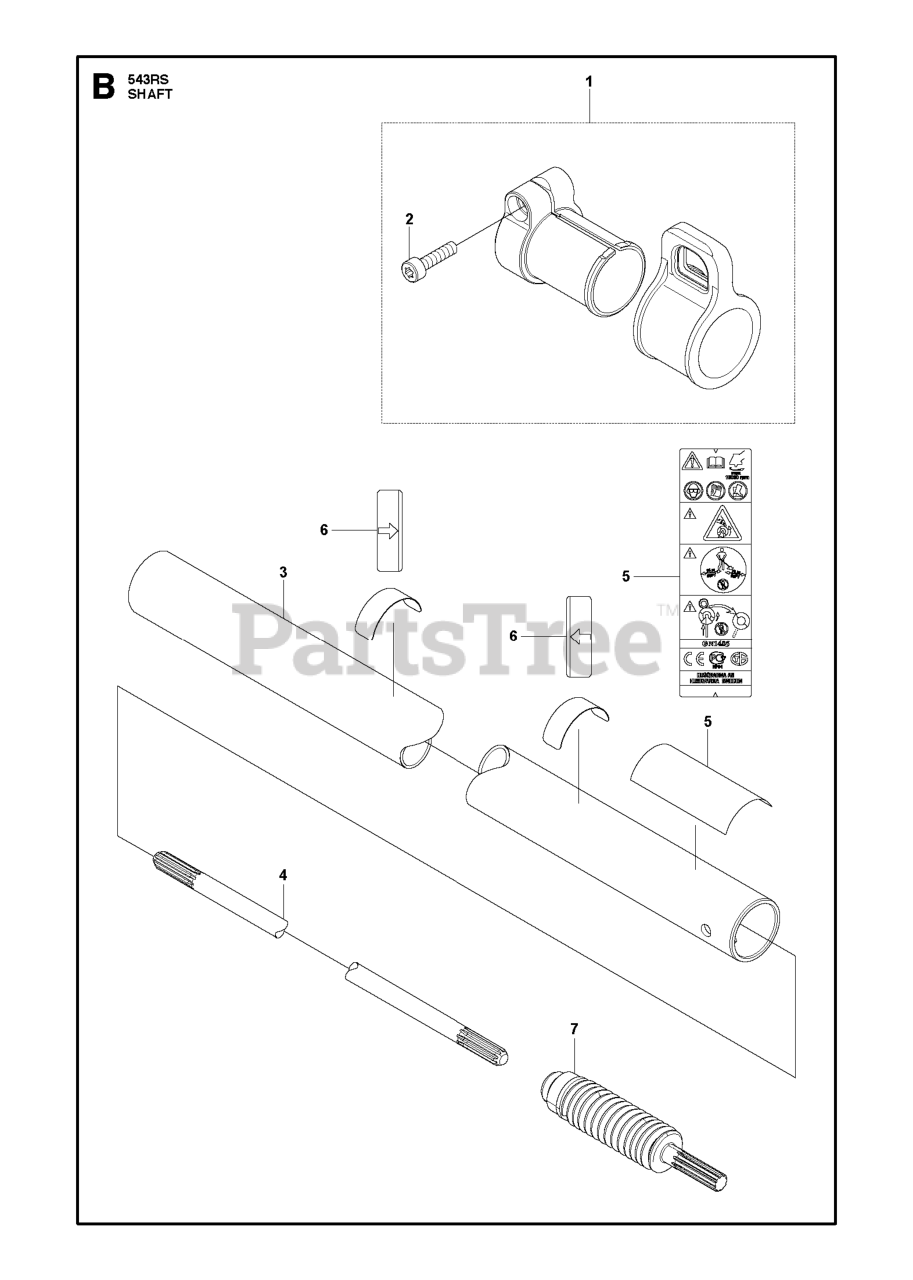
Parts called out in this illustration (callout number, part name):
1	HANGER ASSY.
2	BOLT
5	DECAL
